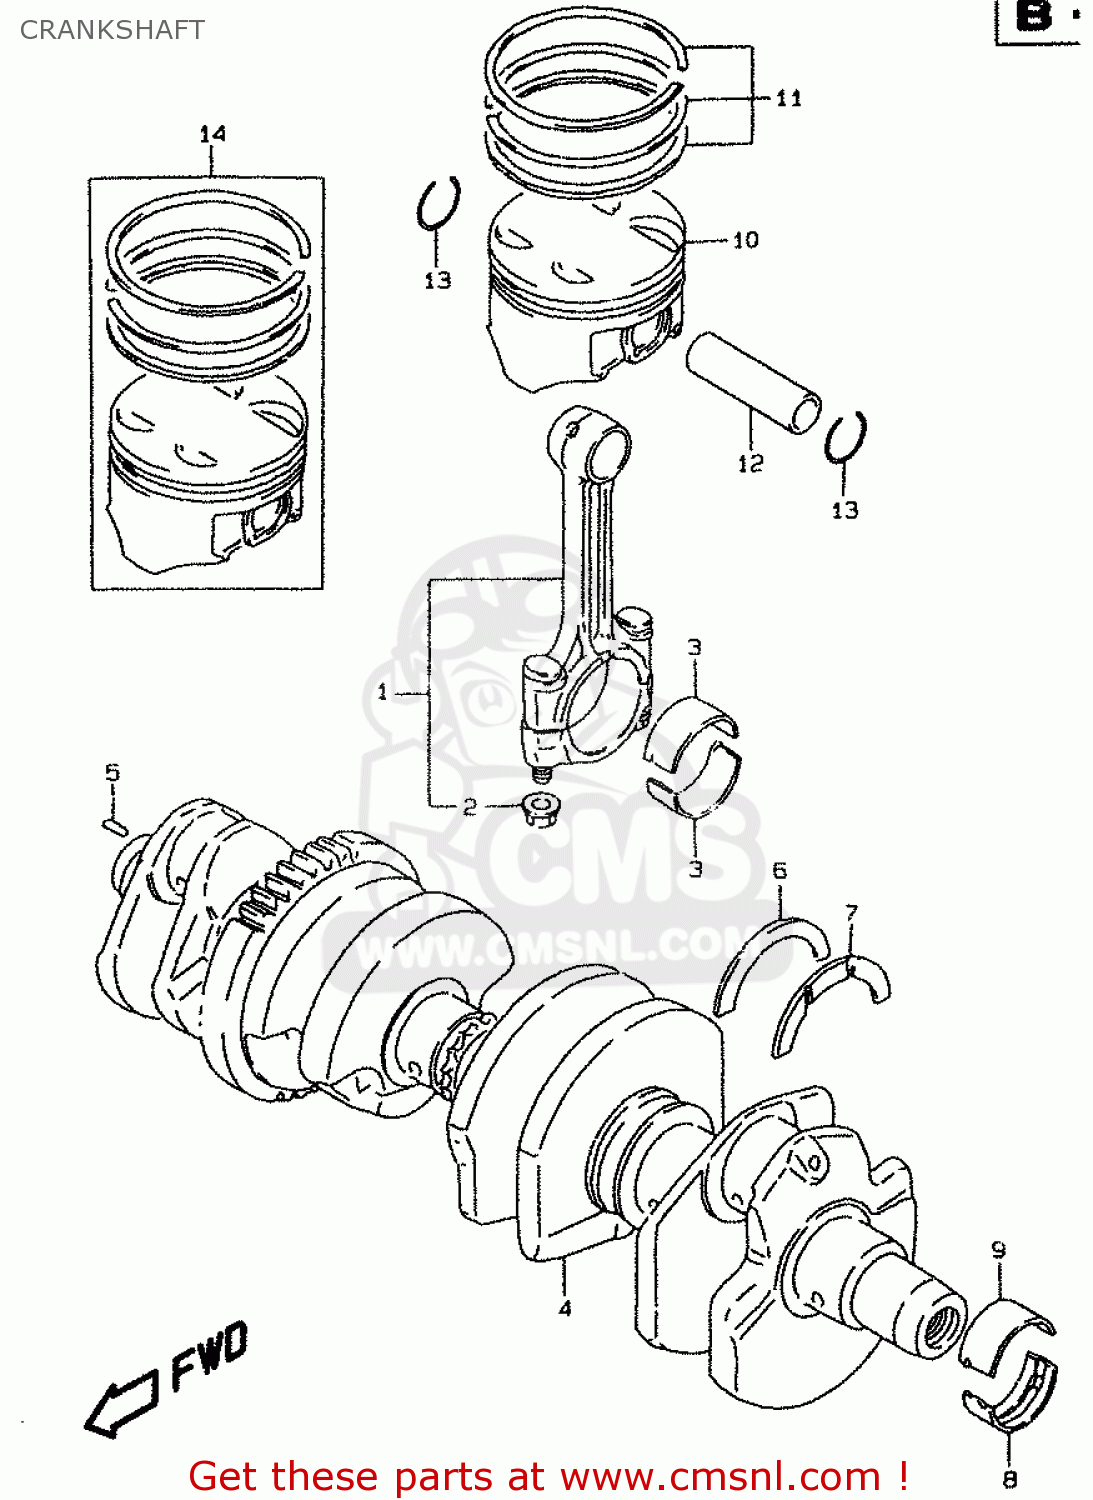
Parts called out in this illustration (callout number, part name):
1	CONNECTING ROD ASSY
2	NUT
3	BEARING,CRANK PIN
4	CRANKSHAFT SET
5	PIN
6	BEARING,CRANK THRUST(GREEN)
7	BEARING,CRANK THRUST(RED)
8	BEARING,CRANKSHAFT LWR
9	BEARING,CRANKSHAFT UPR
10	PISTON
11	RING SET,PISTON
12	PIN,PISTON
13	CIRCLIP,PISTON PIN
14	PISTON SET (OS:0.5)
